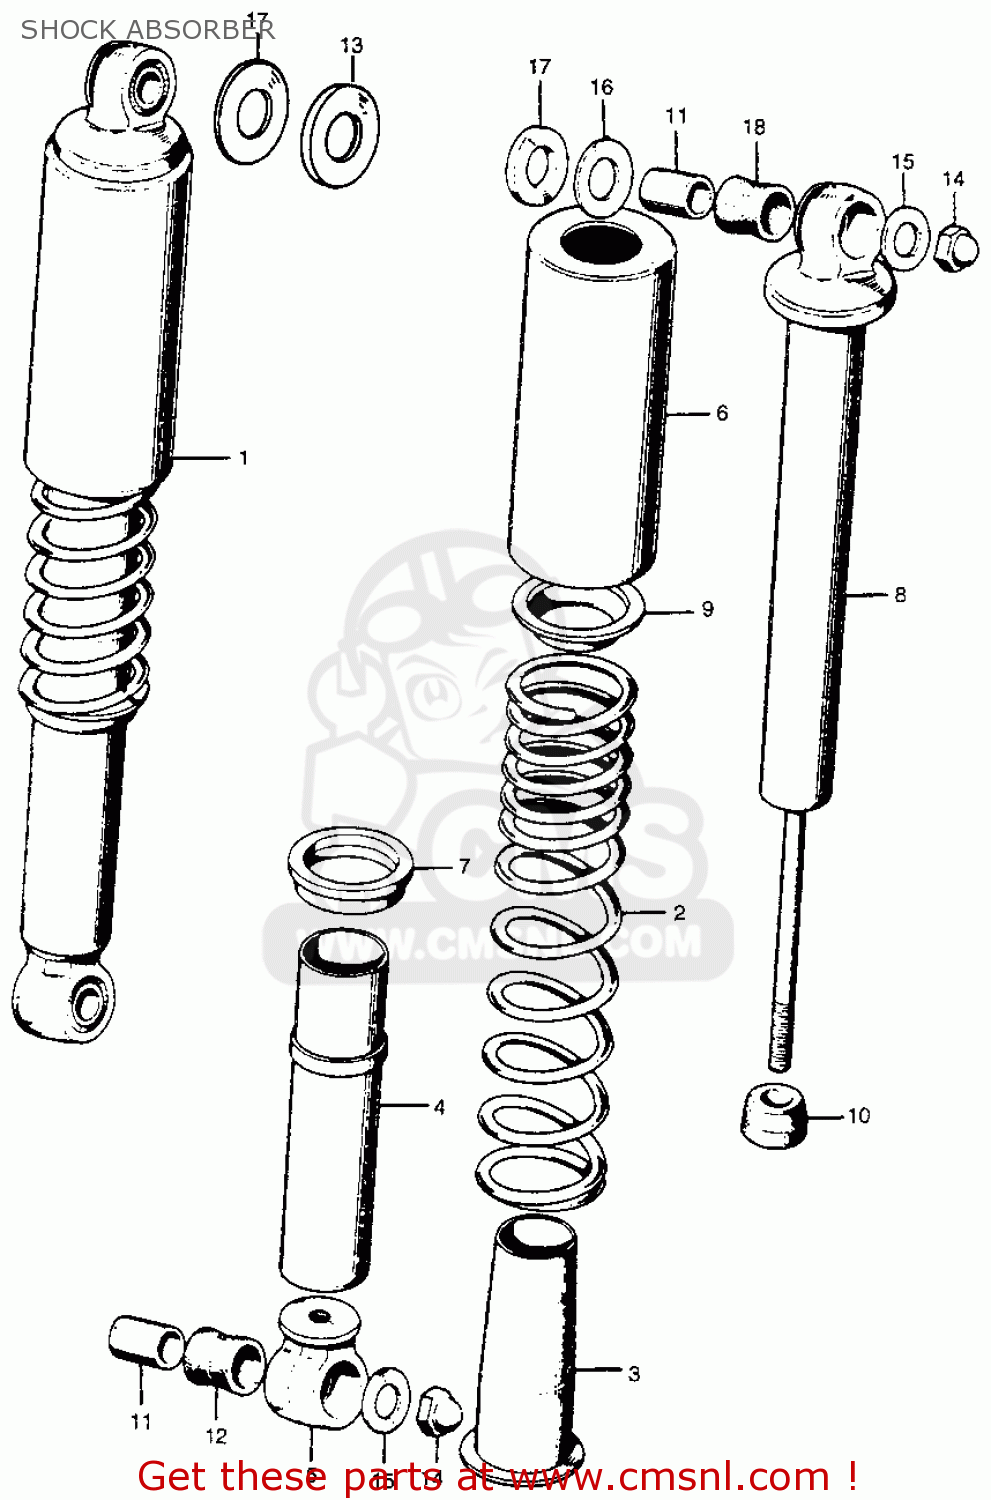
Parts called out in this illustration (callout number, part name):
1	S/ABS ASSY. *Y2C*
2	SPRING, RR. SHOCK
3	GUIDE, CUSHION
4	SEAT, RR. SHOCK
5	METAL, RR. SHOCK
6	CASE, RR. *Y2C*
7	SEAT, RR.
8	DAMPER ASSY., RR.
9	SEAT, RR. SHOCK
10	RUBBER,STOPPER
11	COLLAR, CUSHION
12	BUSH,REAR CUSHION
13	WASHER,12.2X26
14	NUT, 10MM
15	WASHER,10MM
16	WASHER,PLAIN,12MM
